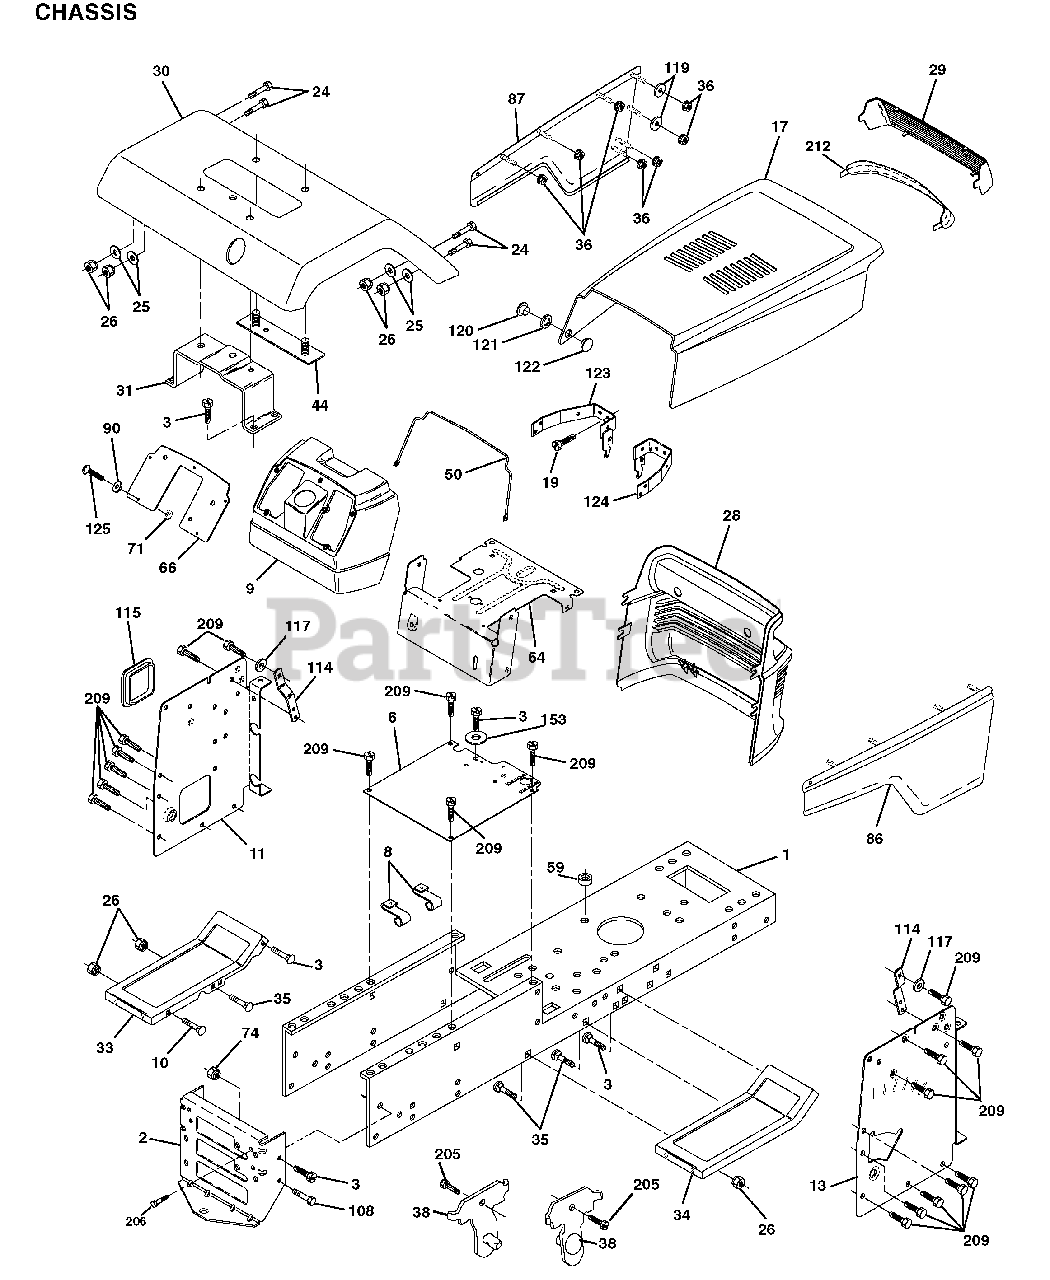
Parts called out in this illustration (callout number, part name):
1	Chassis Wldmt.
2	Drawbar Stretch 94
3	Screw 3/8-16 x 3/4
6	Saddle Flat Lt
8	Clip Insulator
10	Bolt RdHd Sqnk. 3/8-16 Unc x 1
11	Panel Dash Lh
13	Panel Dash Rh
19	Screw Hwhd Hi-Lo #13-16 x 3/4
24	Bolt Fin Hex 3/8-16 Unc x 1 Gr. 5
25	Washer 13/32 x 13/16 x 12 Ga.
26	Nut Lock Hex w/Insert 3/8-16 UNC
28	Grill / Lens Asm
29	Lens Grille
30	Fender Asm YTGT
31	Bracket Fender
33	Footrest Pnt. Lh
34	Footrest Pnt. Rh
35	Bolt RdHd Sht. Sqnk. 3/8-16 x 3/4
36	Nut Pal
37	Screw Thdrol 5/16-18 x 1/2 Tyt
38	Bracket Asm Pivot Mower Rear
44	Strap Asm Fender
50	Rod Support Hood
59	Bushing Snap Split
64	Dash Lower
66	Plate Dash Slkscr.
71	Nut Keps Hex 1/4-20 Unc
74	Nut Crownlock 3/8-16 Unc
86	Panel Asm. Pnt. Side Rh
87	Panel Asm. Pnt. Side Lh
90	Washer 9/32 x 3/4 x 16 Ga.
108	Bolt Fin Hex 3/8-16 Unc x 3/4
114	Bracket Support Dash
115	Cover Access
117	Washer Serrated Disc 13/32 x 1
119	Washer 9/32 x 1-1/4 x 16 Ga.
120	Rivet Ratchet Female
121	Washer Nylon
122	Rivet Ratchet Male
123	Bracket Asm. Pivot Hood Lh
124	Bracket Asm. Pivot Hood Rh
125	Screw Mach Cr. 1/4-20 x 3/4
153	Washer 13/32 x 1-3/8 x 3 Ga.
206	Bolt Shoulder 5/16-18
209	Screw Hex wsh Thdrol 3/8-16 x 3/4
212	Insert Lens Reflector
